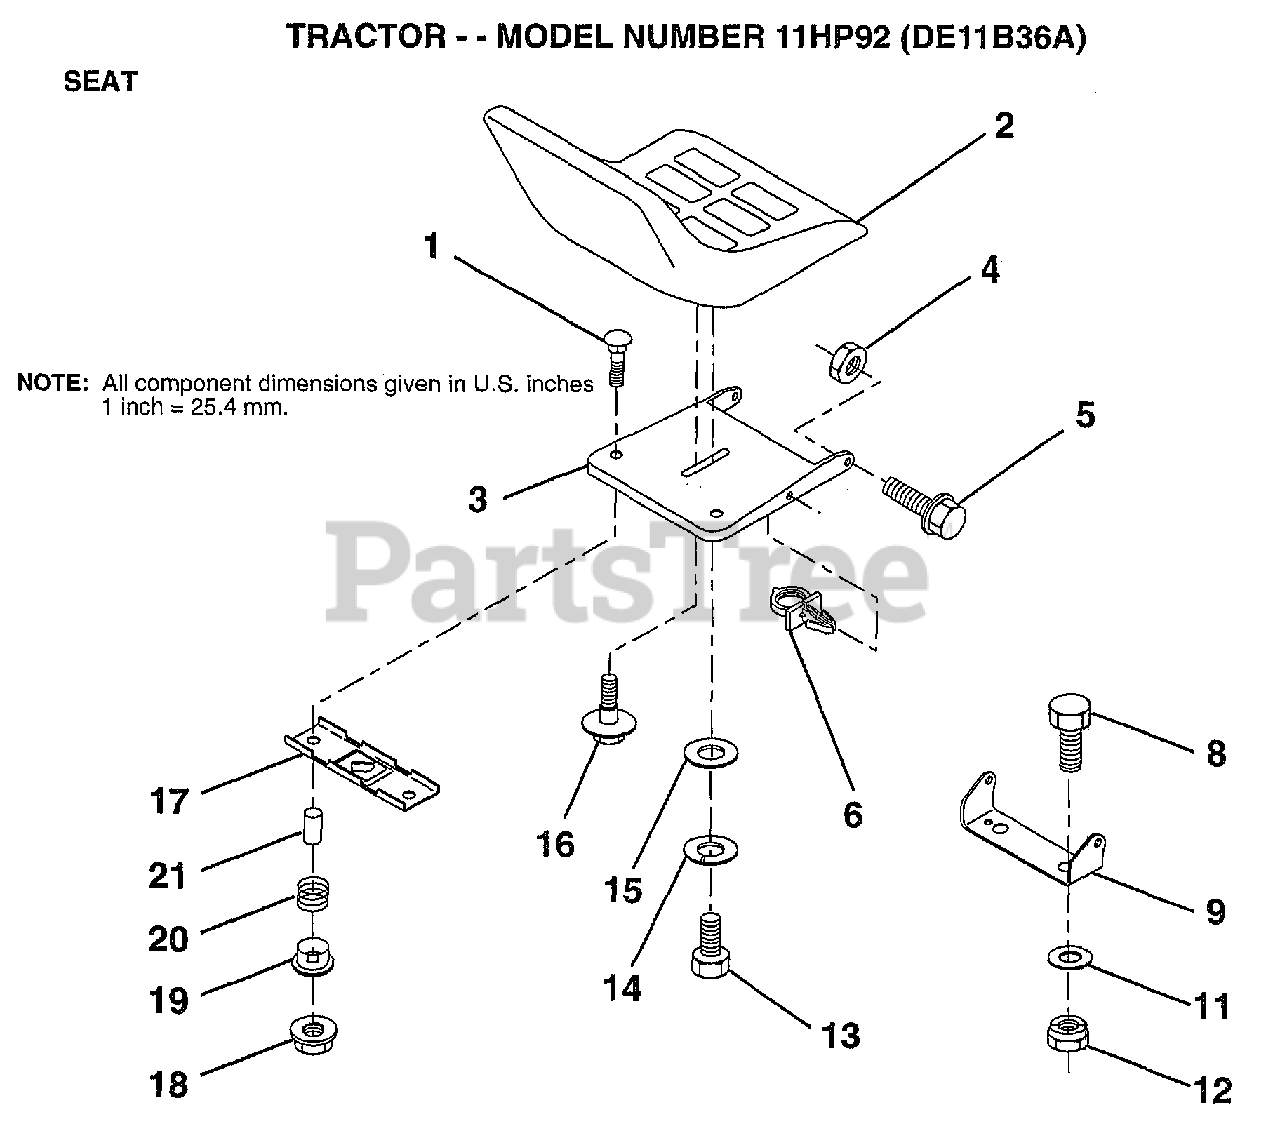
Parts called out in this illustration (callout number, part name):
1	BOLT-RD HD SQ NK
3	PAN-SEAT
4	NUT
5	"BOLT,SHOULDER"
6	CLIP.PUSH-IN.HING
8	BOLT
9	BRACKET PVT SEAT
11	WASHER
12	NUT
13	BOLT
14	LOCKWASHER
15	WASHER
16	"BOLT,SHOULDER"
17	BRKT SWITCH
19	BUSHING
20	SPRING
21	SPLIT SPACER
